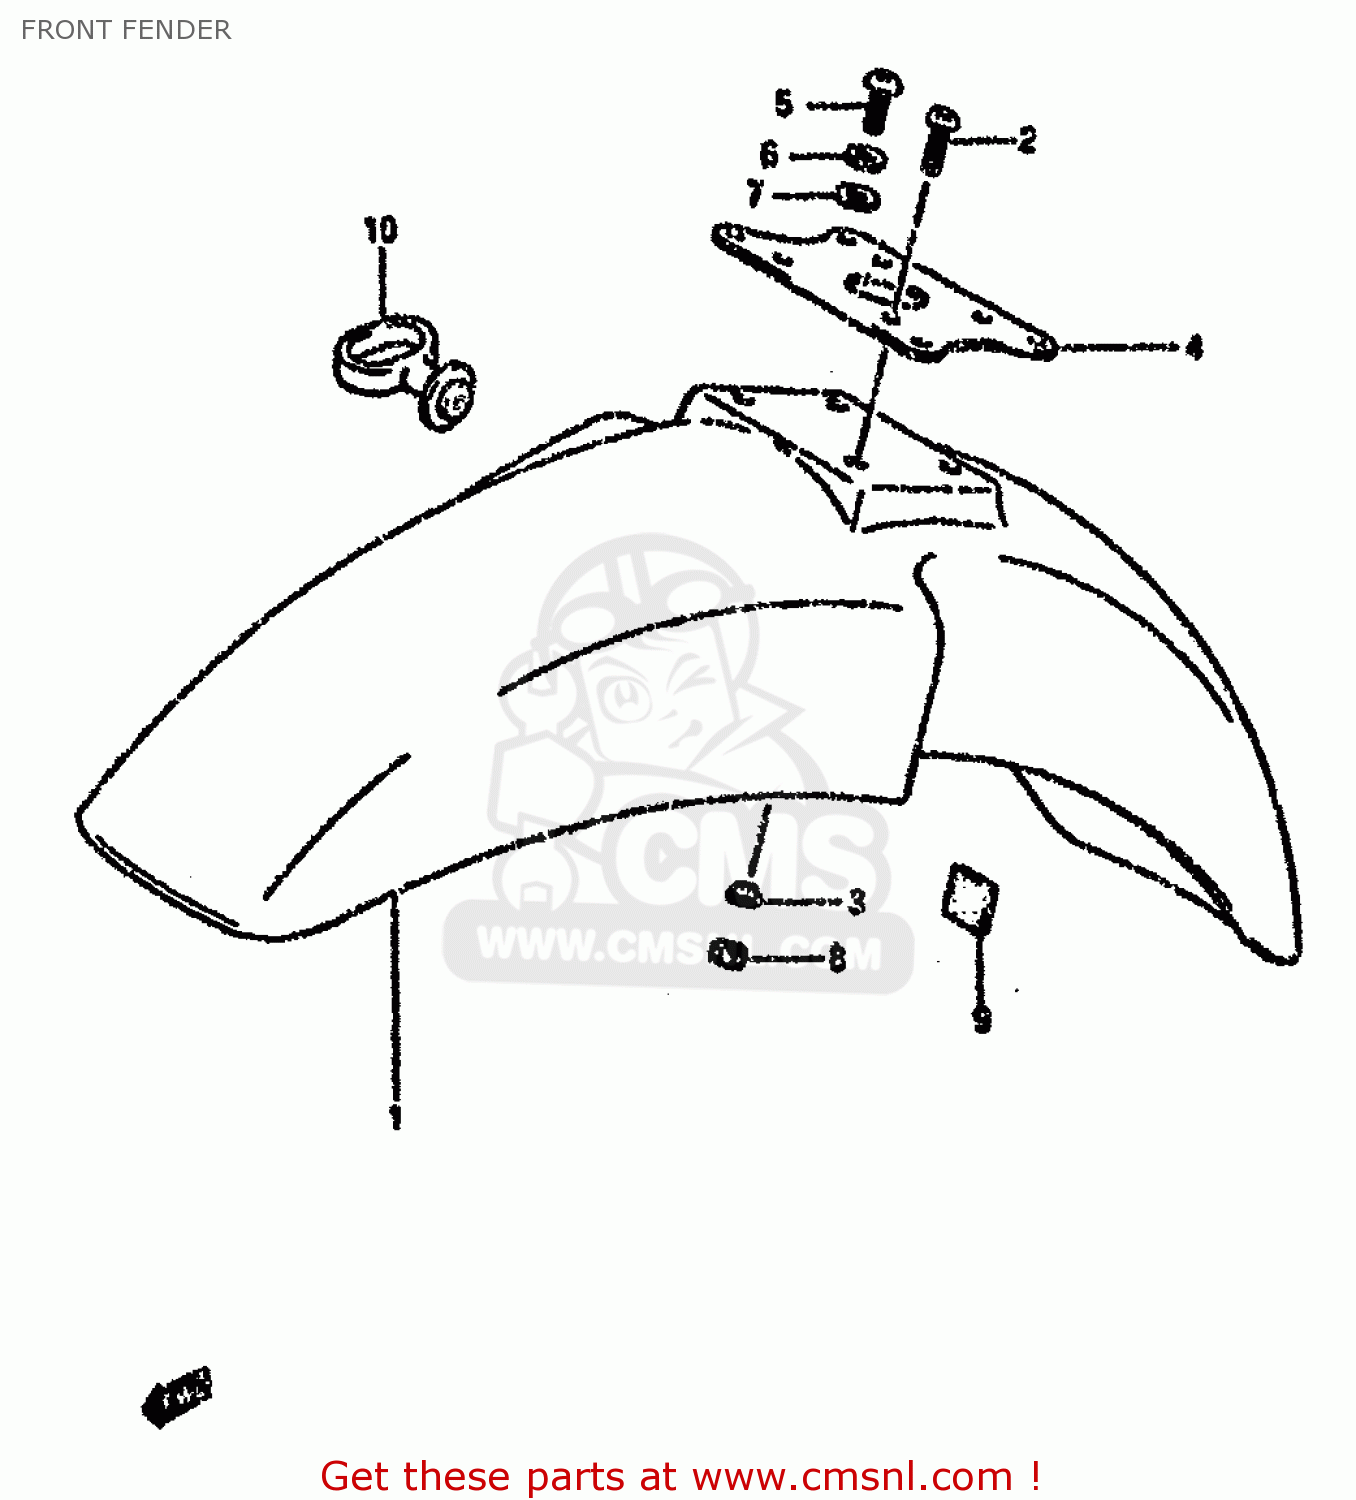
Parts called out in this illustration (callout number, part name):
1	FENDER,FR
2	SCREW(5X14)
3	WASHER
4	BRACE, FRONT FENDER (SILVER)
5	SCREW(5X14)
6	LOCK WASHER
7	WASHER
8	NUT
9	CUSHION, FENDER SIDE
10	GUIDE,CABLE
